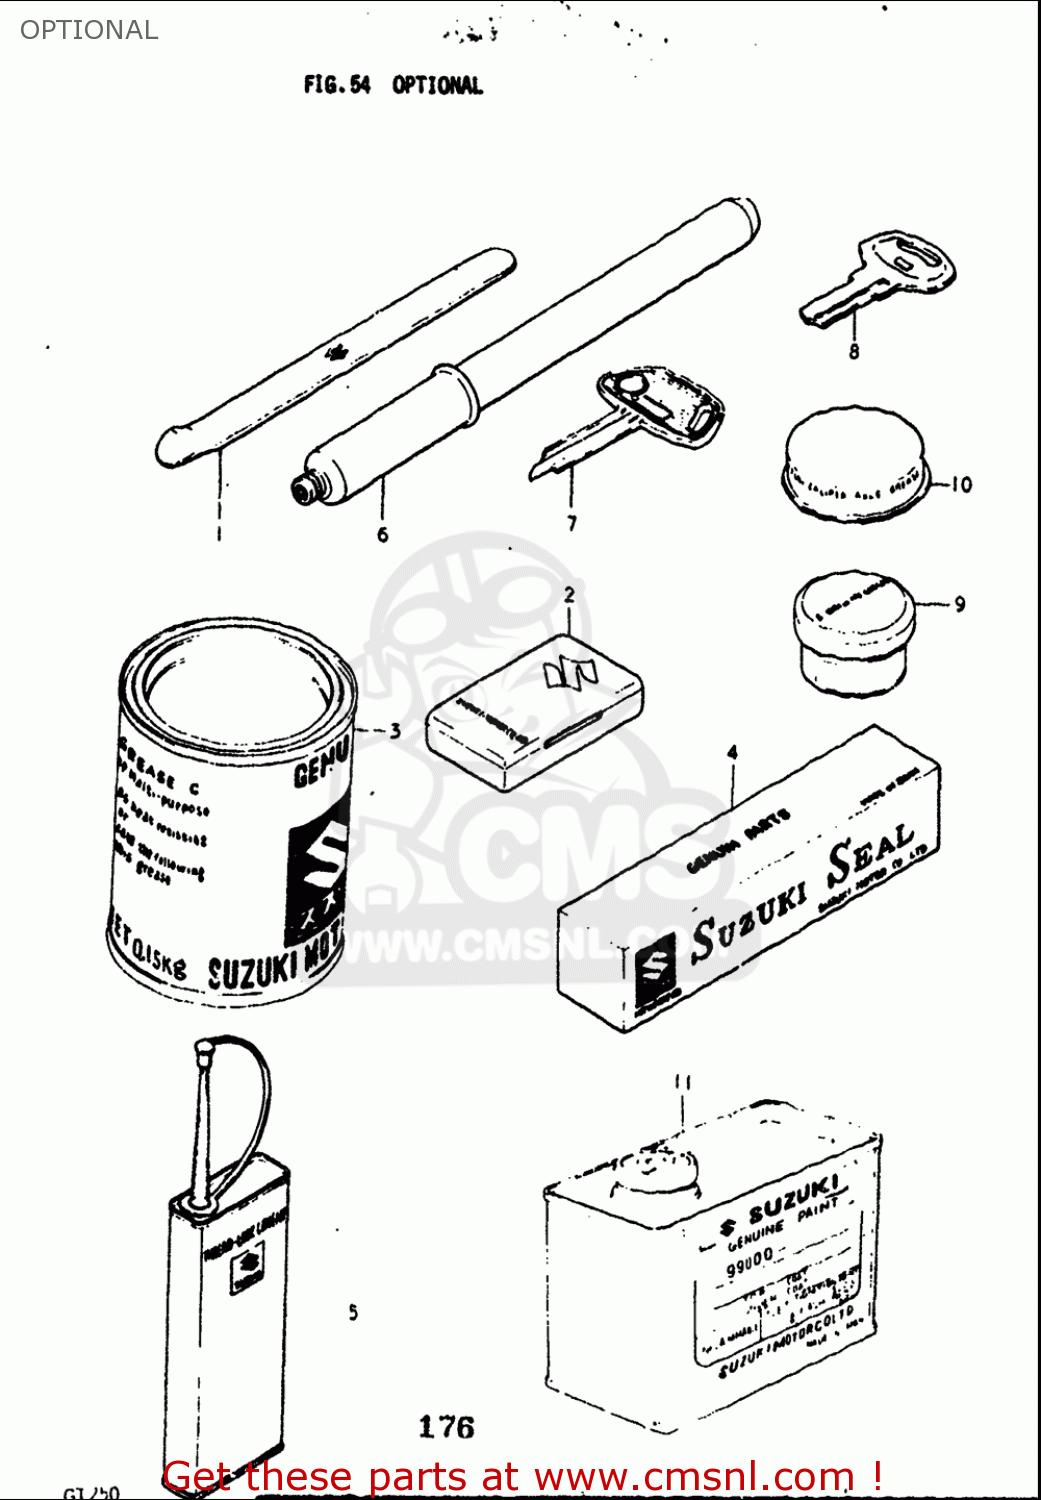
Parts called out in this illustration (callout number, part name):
1	LEVER,TIRE
3	GREASE(C)EP2 LITHIUM 150G
5	THREAD LOCK NO.1401 CLEAR 200G
8	KEY,BLANK
9	GREASE,SILICON 20G
10	GREASE,PBC FOR BRK PAD 20G
